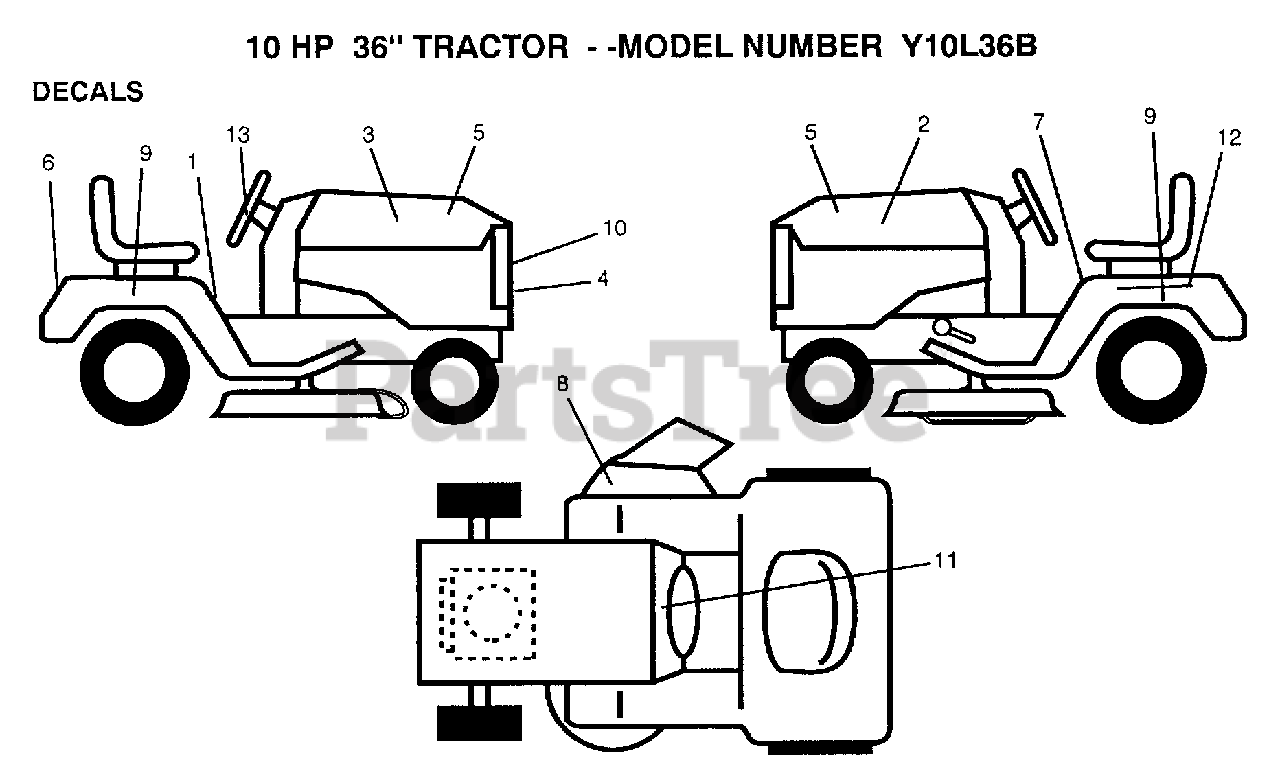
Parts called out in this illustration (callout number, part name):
1	DECAL.CENTER.SHIF
4	DECAL.GRILL
5	DECAL.PANEL.SIDE
7	DECAL CAUTION
8	"DECAL, WARNING"
9	DECAL.FEND.QUICKS
10	DECAL.GRILL.YARDP
12	DECAL
13	DECAL.INSERT.STRG
